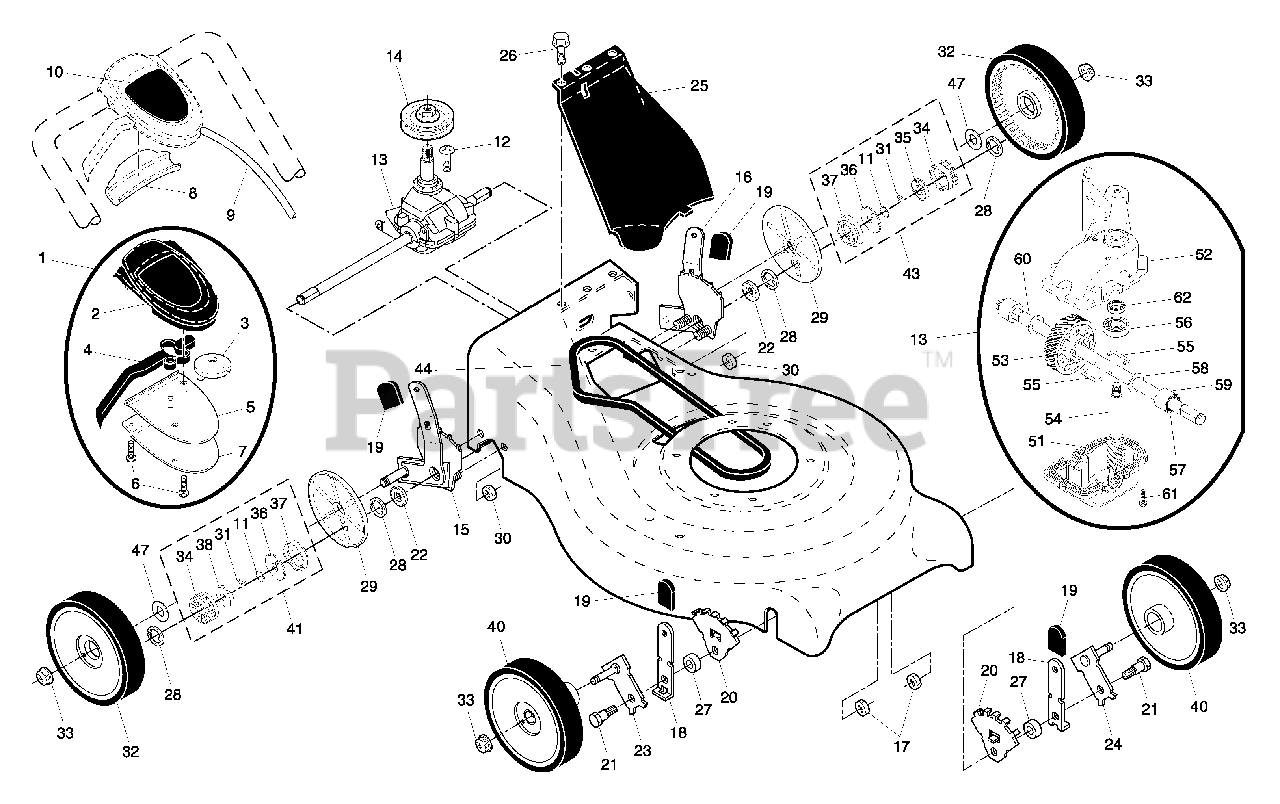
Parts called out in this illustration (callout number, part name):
1	Drive Control Assembly
2	Cover, Top
4	Lever, Drive Control
5	Cover, Bottom
7	Mounting Bracket
8	Cap, Bottom
9	Cable, Drive
10	Decal, Drive Control
11	Spring, Torsion
13	Gear Case Assembly, Complete
14	Pulley, Drive
15	Kit, Wheel Adjuster Assembly, RH
16	Kit, Wheel Adjuster Assembly, LH
17	Nut, Hex
18	Spring, Selector
19	Knob, Selector Spring
20	Bracket, Wheel Adjusting
21	Bolt, Shoulder, Hex Head
22	Bearing, Ball
23	Axle Arm Assembly, RH
24	Axle Arm Assembly, LH
25	Cover Drive
26	Screw, Threaded, Rolled #10-25 x .50
28	E-Ring 7/16
29	Cover, Dust, Wheel
30	Nut, Hex
32	Wheel & Tire Assembly, Rear 8 x 1-3/4
33	Nut, Flangelock 3/8-16
35	Retainer, Drive, LH
36	Disc, Drive
37	Seal, Friction
38	Retainer, Drive, RH
40	Wheel & Tire Assembly, Front 8 x 1-3/4
41	Pinion Assembly, RH
43	Pinion Assembly, LH
51	Case, Lower
52	Case, Upper
53	Gear, 24 Teeth
54	Shaft, Input
55	Wire, Formed
56	Bearing, Ball
57	Seal, Output Shaft
60	Shaft, Output
62	Seal, Input Shaft
